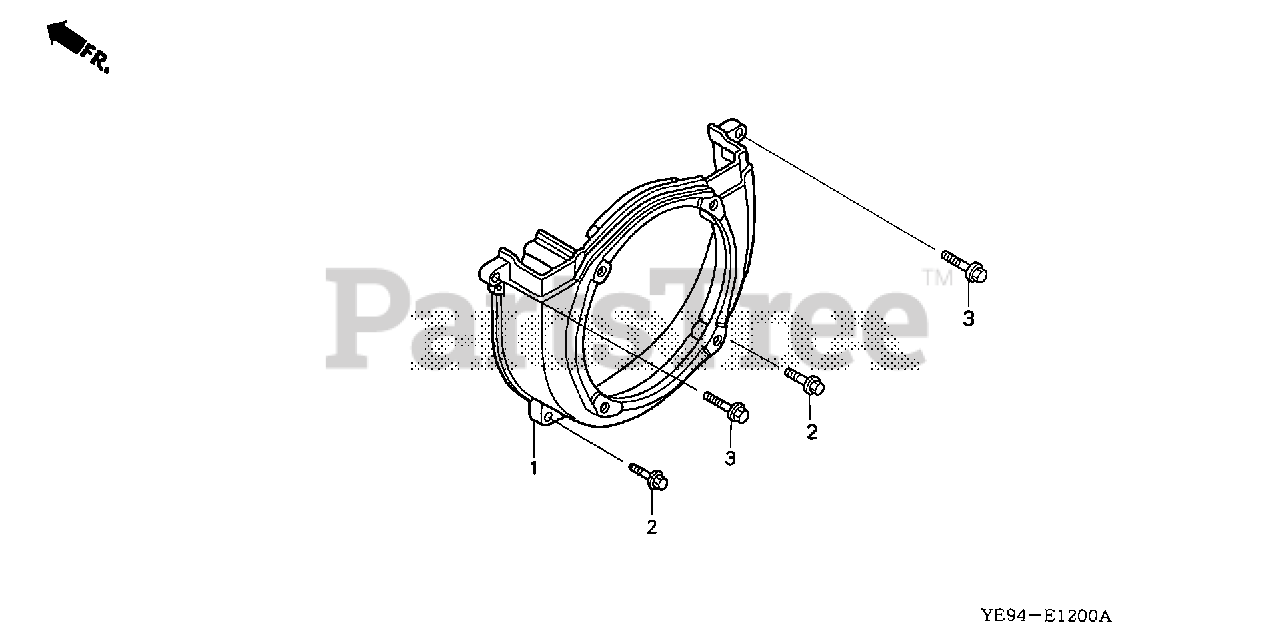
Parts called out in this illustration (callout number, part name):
1	COVER, FAN
2	BOLT, FLANGE (5X18)
3	BOLT, FLANGE (5X22)
